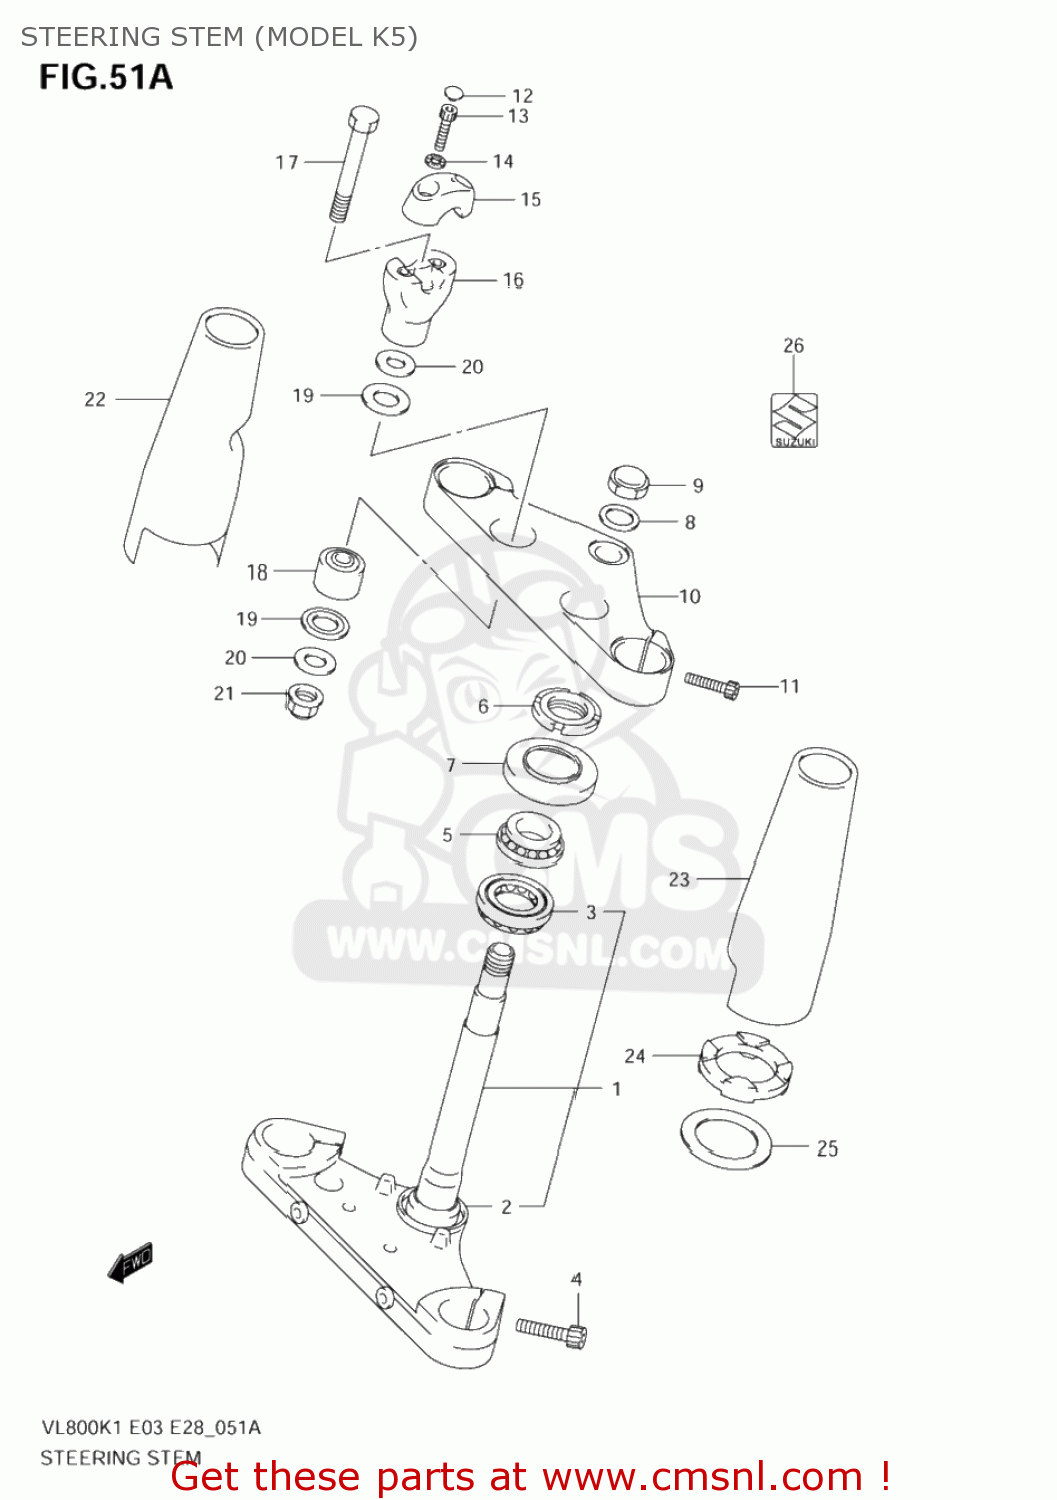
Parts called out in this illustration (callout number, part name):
1	STEM,STEERING
2	SEAL,STEERING LWR
3	BEARING(30X55X17)
4	BOLT
5	BEARING(25X47X15)
6	NUT,STEERING STEM(25X44X10)
7	DUST SEAL,STEERING UPR
8	WASHER(22.5X32X1.6)
9	NUT,CAP
10	HEAD,STEERING STEM
11	BOLT
12	CAP(OD:14.5)
13	BOLT
14	WASHER
15	HOLDER,HANDLE UPR
16	HOLDER,HANDLE UNDER
17	BOLT
18	DAMPER,RUBBER
19	SEAT,RUBBER
20	WASHER
21	NUT
22	COVER,UPR,R
23	COVER,UPR,L
24	SEAT,RUBBER
25	WASHER
26	EMBLEM,S
